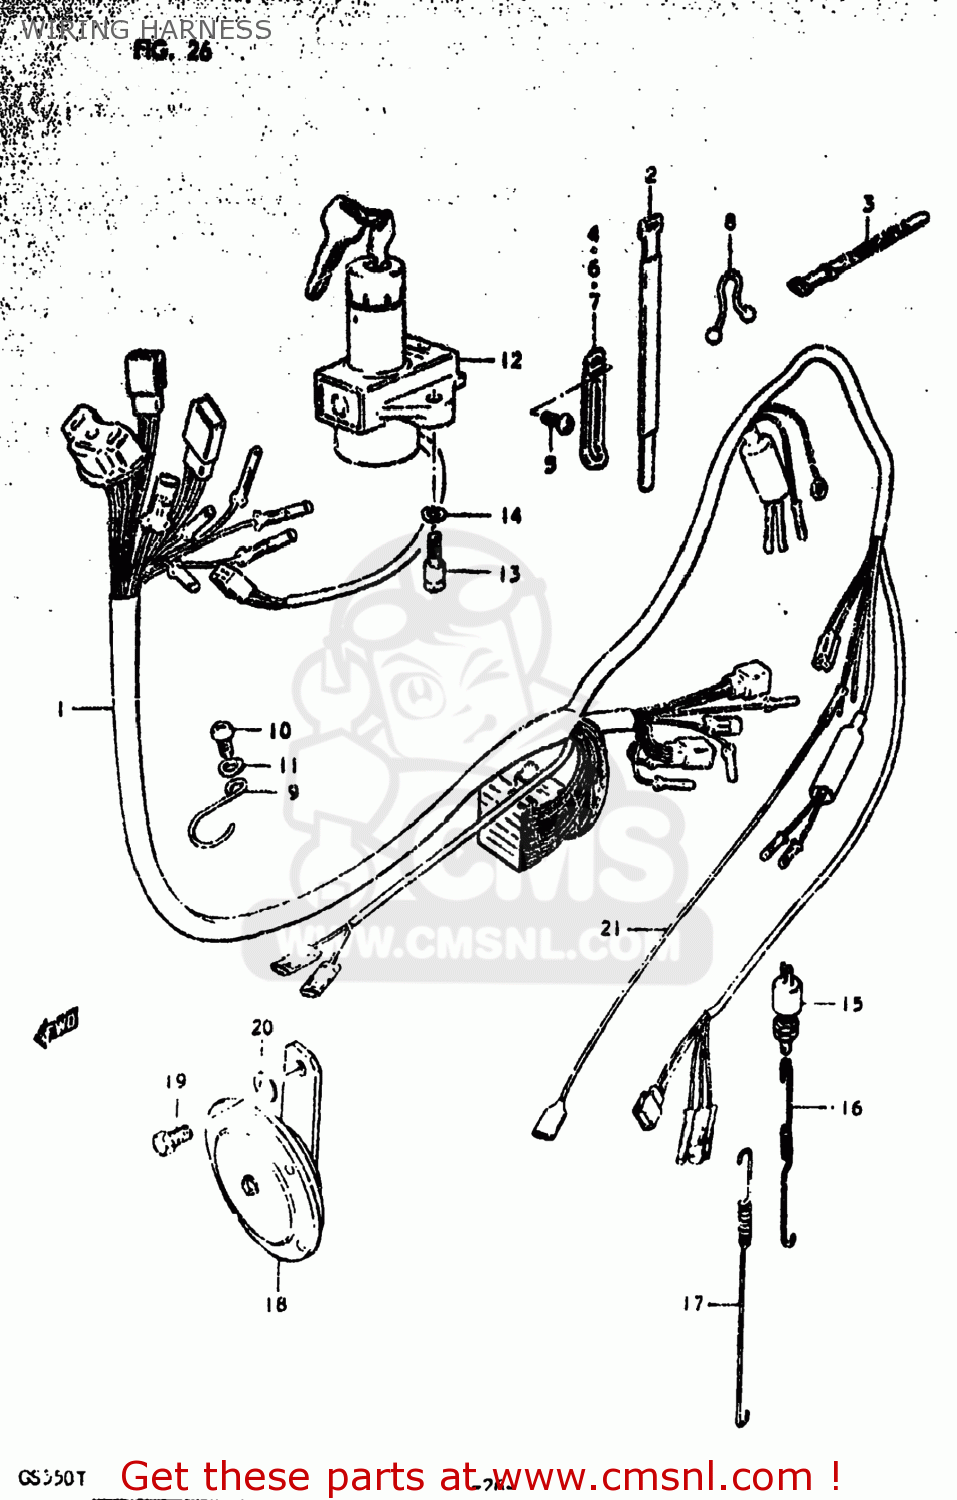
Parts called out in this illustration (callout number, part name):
1	HARNESS,WIRING
2	CLAMP
3	CLAMP(L:120)
4	CLAMP
5	SCREW
6	CLAMP
7	CLAMP
8	CLAMP
9	GUIDE,WIRING HARNESS
10	SCREW 6X12
11	WASHER 6MM
12	LOCK ASSEMBLY,STEERING
13	BOLT
14	LOCK WASHER
15	SWITCH ASSY,BRAKE LAMP
16	SPRING
17	SPRING
18	HORN ASSEMBLY,LOW PITCH
19	BOLT 8X12
20	WASHER
21	WIRE
